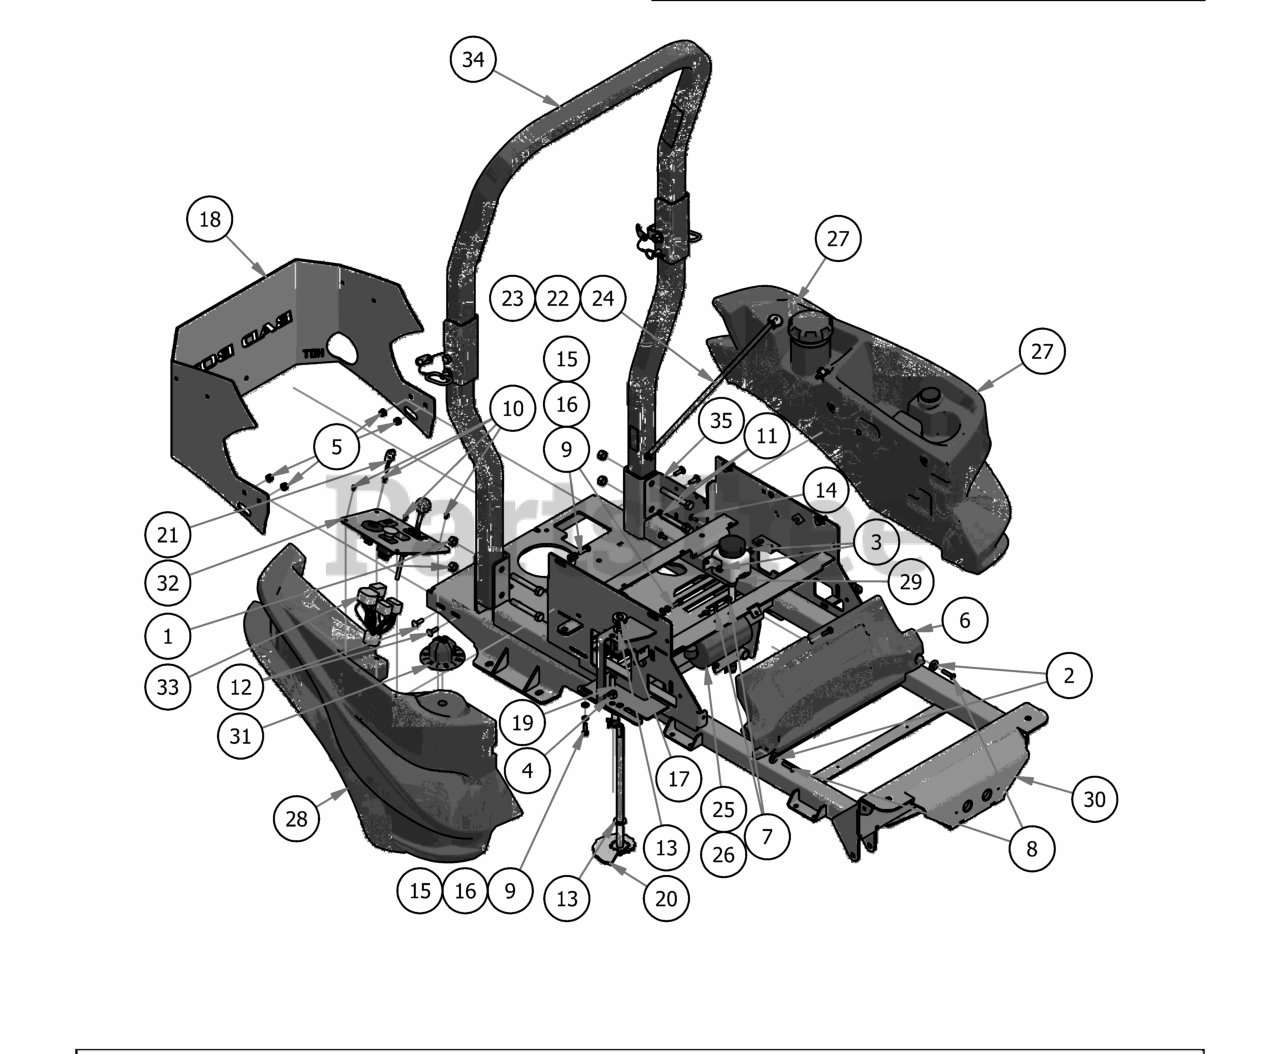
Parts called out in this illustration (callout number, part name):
1	1/2" Center Lock Nut
2	1/2" Flat Washer Flat Black
3	1/4-20 Nylon Insert flange Nut
4	1/2" Hex Nut
5	5/16-18 Nylon Flange Nut
6	Front Cover
7	M6-1.0 X 16MM Hex Bolt
8	5/16-18x1.5 torx cutter -Black
9	5/16" x 1" Bolt
10	10-32 x 3/8" Button Socket Head Bolt
11	1/2-13 x 3 1/2 GR 5 Hex Bolt
12	5/16" x 1" Carriage Bolt
13	.630 ID x 1.122 OD x .142 THK Plastic Washer
14	1/4" x 3/4" Carriage Bolt
15	5/16" Flat Washer
16	5/16" Lock Washer
17	5/8" Split Collar
18	2017 ZT Rear Plate
19	Dial Rod Plunger
20	ZT Deck Height Bar Assembly
21	Ignition Key
22	Maverick Honda Fuel Line Assy-54"
23	Maverick Kohler Fuel Line Assy-37"
24	Maverick Kawasaki Fuel Line Assy-15"
25	ZT/Mav EPA Cannister Assy
26	2019 Honda Maverick EPA Cannister Assy
27	Left Fuel Tank
28	Right Side Console
29	Hydro Tank Assembly
30	2018 Maverick Frame
31	MZ/ZT Deck Height Dial
32	2019 ZT/Maverick Control Panel Assembly
33	Wiring Harness
34	2016 2x2 ROPS
35	Honda Rectifier Mount
